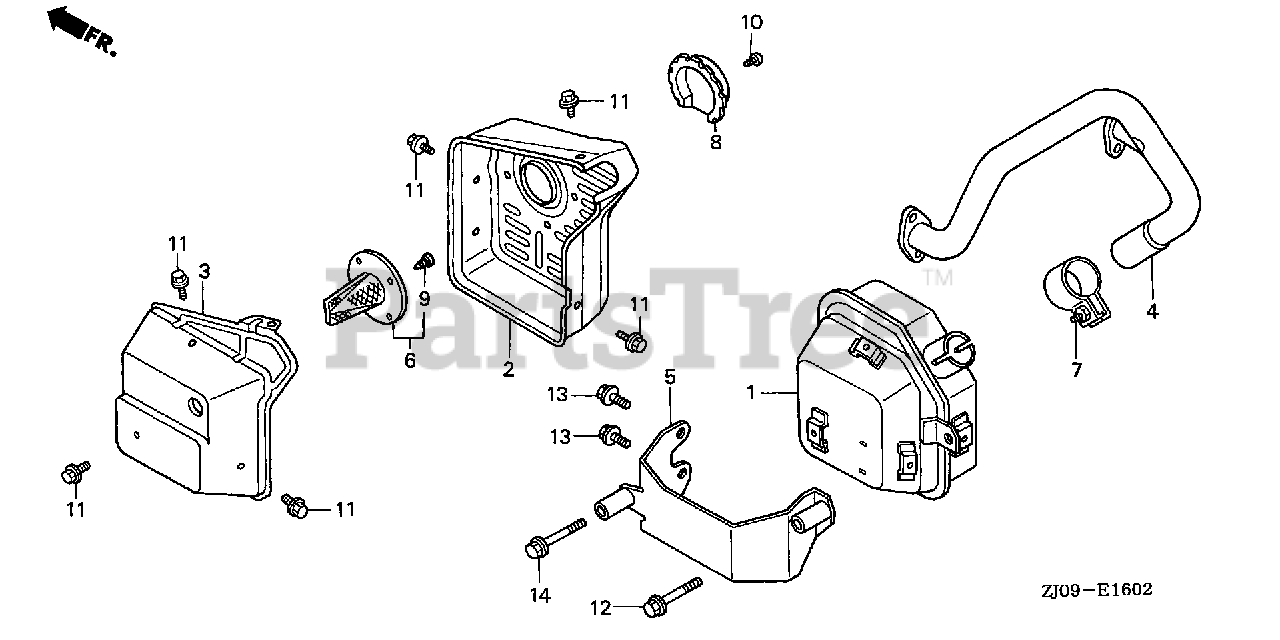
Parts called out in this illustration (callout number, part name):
1	MUFFLER (SIDE-L)
2	PROTECTOR, MUFFLER (SIDE-L)
3	PROTECTOR, RR. MUFFLER (SIDE-L)
4	PIPE, EX. (SIDE-L)
5	STAY, MUFFLER (SIDE-L)
6	ARRESTER, SPARK (SIDE)
7	BAND ASSY.
8	DEFLECTOR KIT, EX.
9	SCREW (NELSON)
10	SCREW, TAPPING (4X8)
11	BOLT, FLANGE (6X8)
12	BOLT, FLANGE (6X50)
13	BOLT, FLANGE (8X14)
14	BOLT, FLANGE (8X50)
